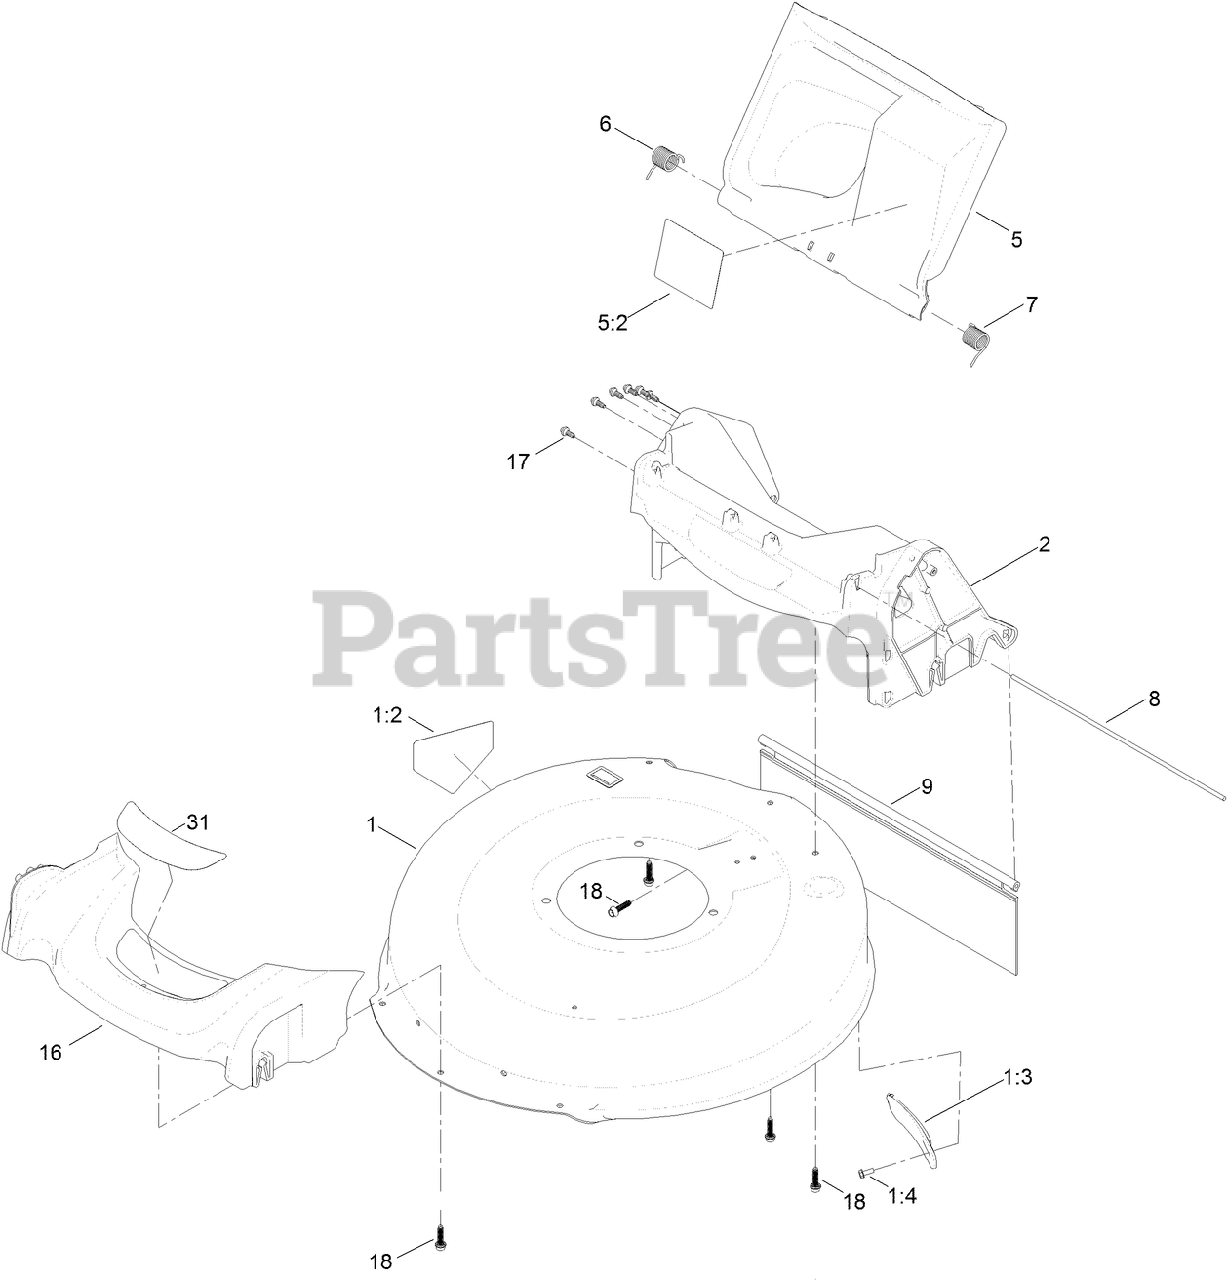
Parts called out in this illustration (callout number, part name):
1	HOUSING ASM
1:2	DECAL-DANGER
1:3	COVER-BELT
1:4	SCREW-TAPTITE
2	CHUTE ASM
5	REAR DEFLECTOR ASM
5:2	DECAL-WARNING
6	SPRING-TORSION
7	SPRING-TORSION
9	SHIELD-TRAILING
18	SCREW-FLANGE, PLASTIC
31	DECAL-DECK
